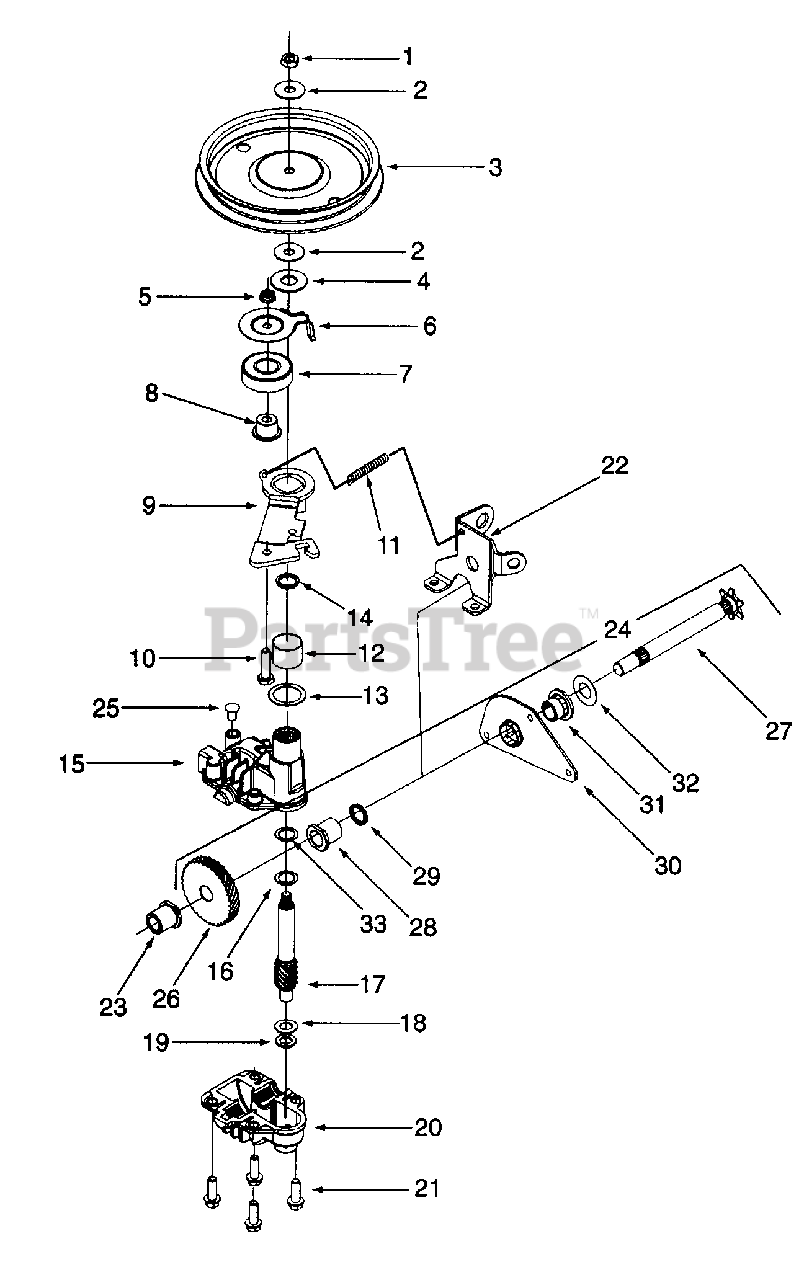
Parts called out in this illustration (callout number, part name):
1	Hex Jam Nut 5/16-24
2	Bell Washer .325 x .930
3	Pulley
4	Flat Washer .510 x 1.120
5	Hex Jam Nut 1/4-28
6	Belt Keeper
7	Bearing
8	Flange Spacer
9	Idler Bracket Assembly
10	Hex Cap Screw 1/4-28 x 1.0
11	Extension Spring
12	Bearing Sleeve
13	Flat Washer .885 x 1.45
14	Oil Seal
15	Upper Housing Assembly
16	Thrust Washer .504 x .70
17	Pinion Shaft 10T
18	Thrust Washer 3/8 x .70
19	Thrust Washer .388 x .625
20	Lower Housing Assembly
21	Hex Screw 1/2-20 x .75
24	Shaft Assembly
26	Gear 34T
27	Output Shaft 6T
28	Flange Bearing
29	Oil Seal
30	Pivot Bracket
31	Flange Bearing
32	Flat Washer .508 ID x 1.0 OD
33	Bearing
